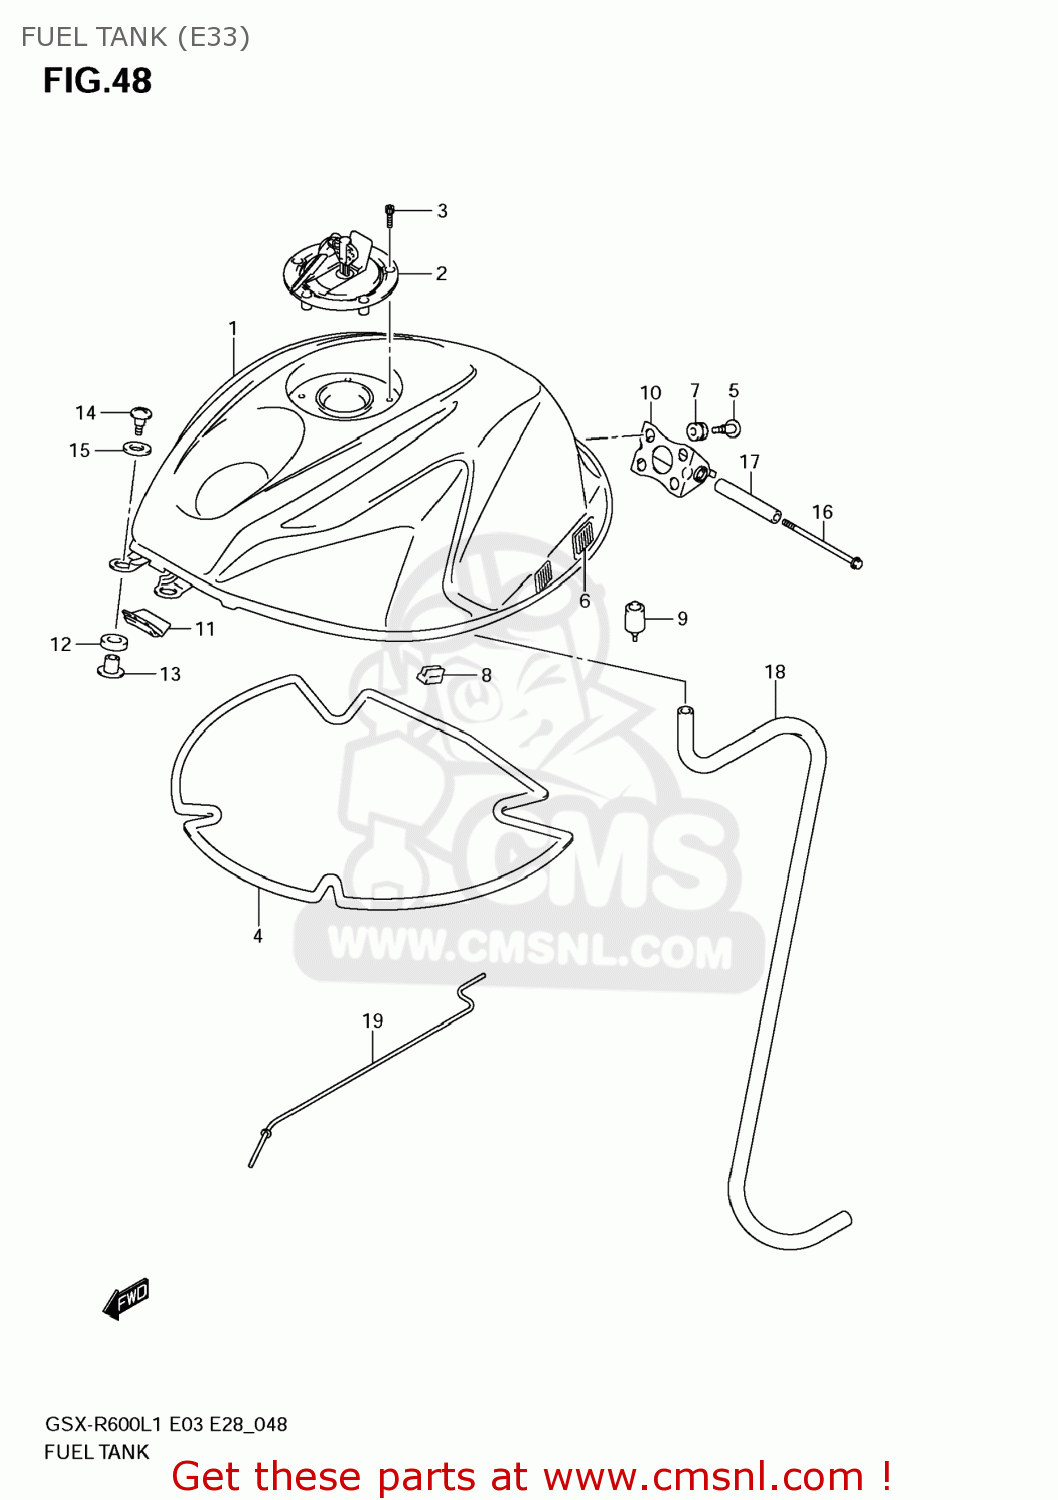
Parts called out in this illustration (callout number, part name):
1	TANK ASSY,FUEL(
2	CAP SET,FUEL TANK
3	BOLT(5X20)
4	SHIELD,FUEL TANK HEAT
5	SCREW,FUEL TANK RR BRACKET
6	FASTENER
7	CUSHION
8	CUSHION,FUEL TANK COVER
9	CUSHION,FUEL TANK RR
10	BRACKET,FUEL TANK NO.1
11	RUBBER,FUEL TANK FR
12	CUSHION,FUEL TANK FR
13	SPACER,FUEL TANK FR
14	SCREW(6X25)
15	WASHER(6.5X22X1.6)
16	BOLT(6X110)
17	SPACER,FUEL TANK RR
18	HOSE,FUEL TANK WATER DRAIN
19	STAY,FUEL TANK
